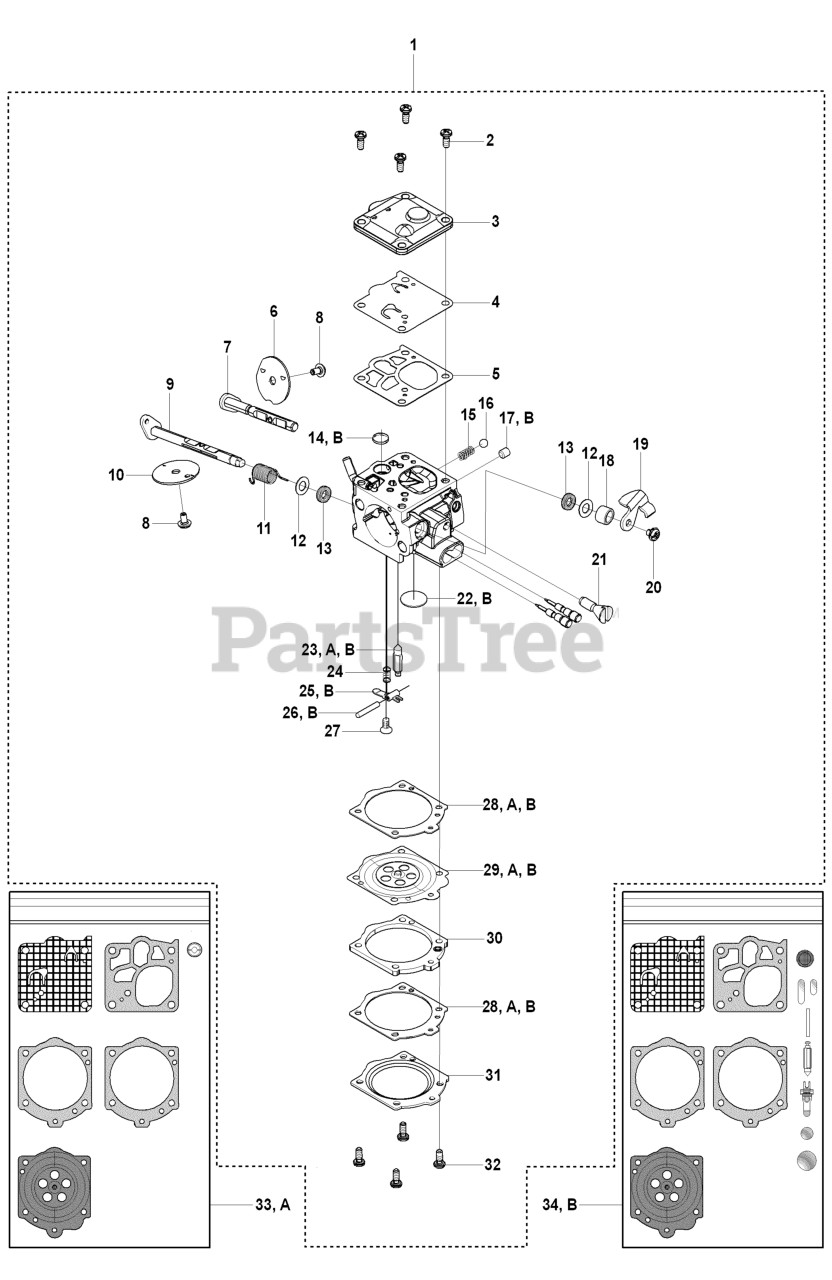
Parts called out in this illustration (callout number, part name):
1	%CARBURETOR
2	SCREW W/ WASHER
3	COVER
4	DIAPHRAM PUMP
5	GASKET
14	FUEL INLET SCREEN
22	WELCH PLUG
23	VALVE INLET NEEDLE
24	SPRING-METER.LEVER
25	LEVER
26	PIN
28	GASKET
29	DIAPHRAM PUMP
33	GASKET KIT
34	REPAIR KIT
